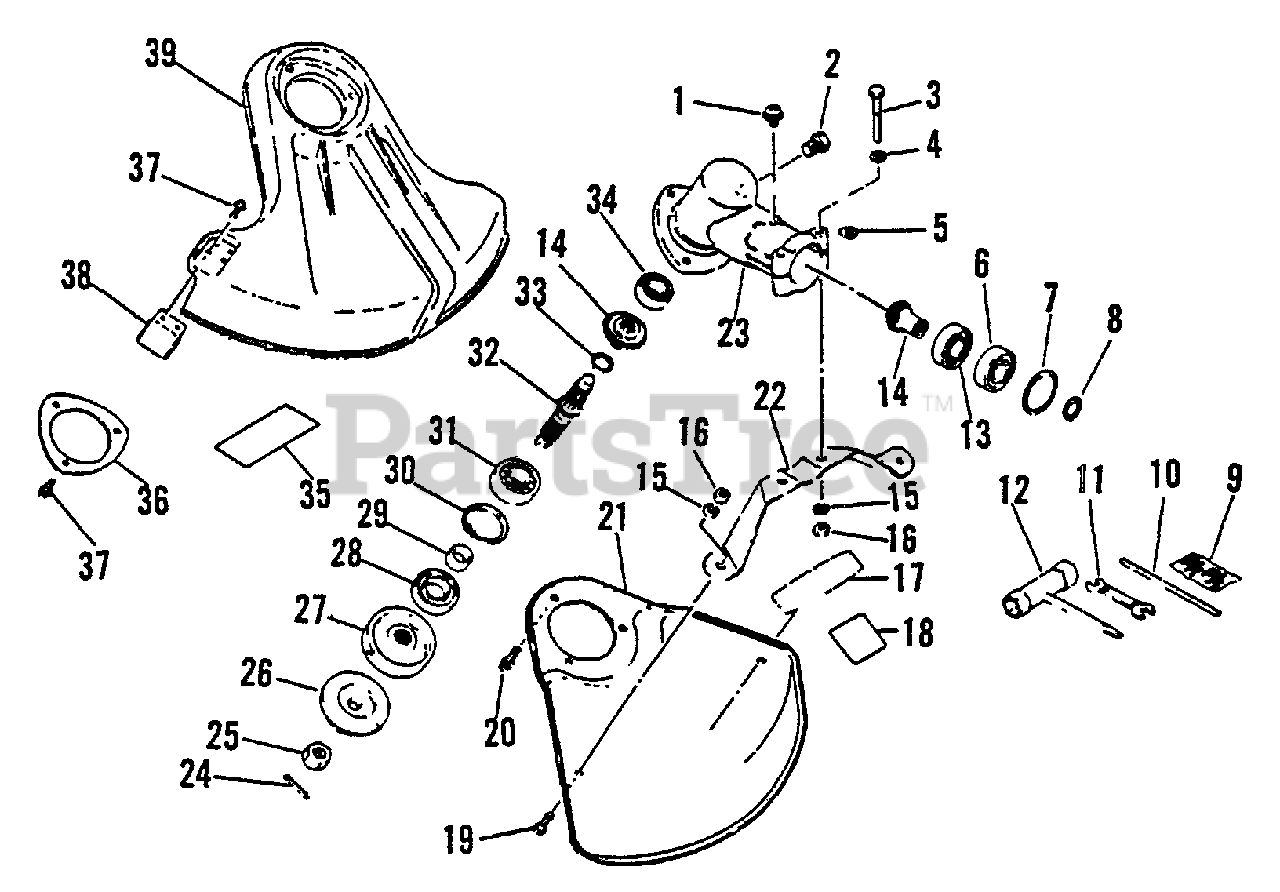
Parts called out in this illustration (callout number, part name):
1	SCREW - 5X10
2	BOLT - 8X8
3	BOLT - 5X40
4	WASHER - 5
6	BEARING, BALL - 6001
7	RING, RETAINING - 28
8	RING, RETAINING - 12
9	PIN, SPLIT - 2X22
10	LOCKING TOOL
11	SPANNER - 8X10mm
12	T-WRENCH - 17X19mm
13	BEARING, BALL - 6001
14	GEAR SET - BEVEL
15	LOCKWASHER - 5
17	LABEL - ECHO
18	LABEL - CAUTION
19	SCREW - 5X8
20	SCREW - 5X10
21	DEBRIS SHIELD KIT
22	BRACKET, SHIELD
23	CASE, GEAR
24	PIN, SPLIT - 2X22
25	NUT - 10 -- LEFT HAND
26	ADAPTOR, BLADE - LOWER
27	ADAPTOR, BLADE - UPPER
28	SEAL, OIL
30	RING, RETAINING - 32
31	BEARING, BALL - 6201
32	GEAR - SHAFT
33	RING, RETAINING - 12
34	BEARING, BALL - 6000
35	LABEL - CAUTION
36	PLATE, SHIELD
37	SCREW - 5X16
38	KNIFE, TRIMMER LINE
39	SHIELD, DEBRIS - PLASTIC
